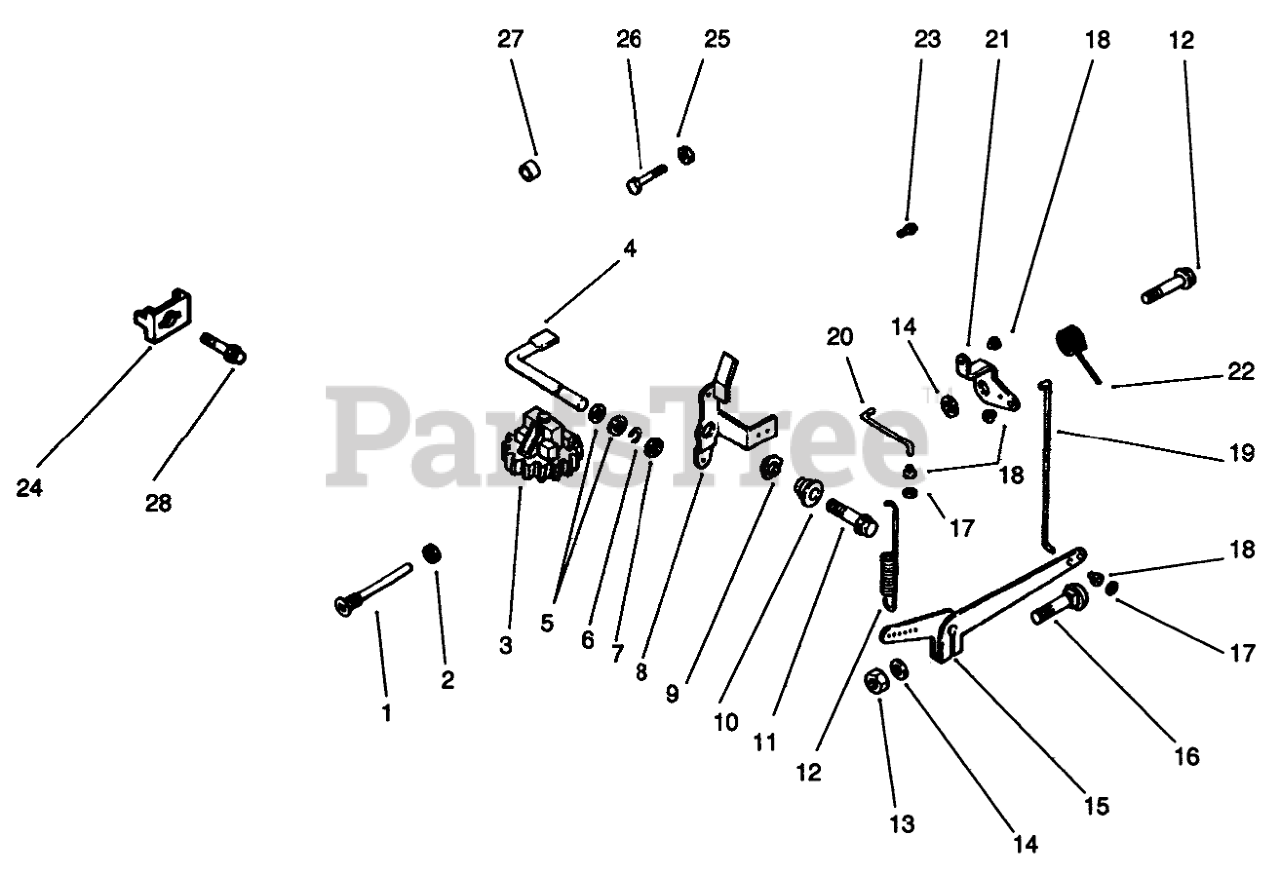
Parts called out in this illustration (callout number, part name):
1	Pin-GovemorStop
2	Washer
3	Governor Gear
4	Shaft-Govenor
5	Washer
6	Retainer-Governor
7	Washer
8	Lever-Speed Control
9	Washer
10	Bushing-Throttle Control
11	Screw-Hex Washer Hd.
12	Spring Governor
14	Washer
15	ARm-Governor
16	Screw-Round Hd.
18	Bushing
19	Linkage-Governor
20	Linkage-Throttle
21	Lever-Throttle
22	Spring-Torsion
23	Screw
25	Nut
26	Screw-Hex Hd.
28	Screw-Hex Wash. Hd.
